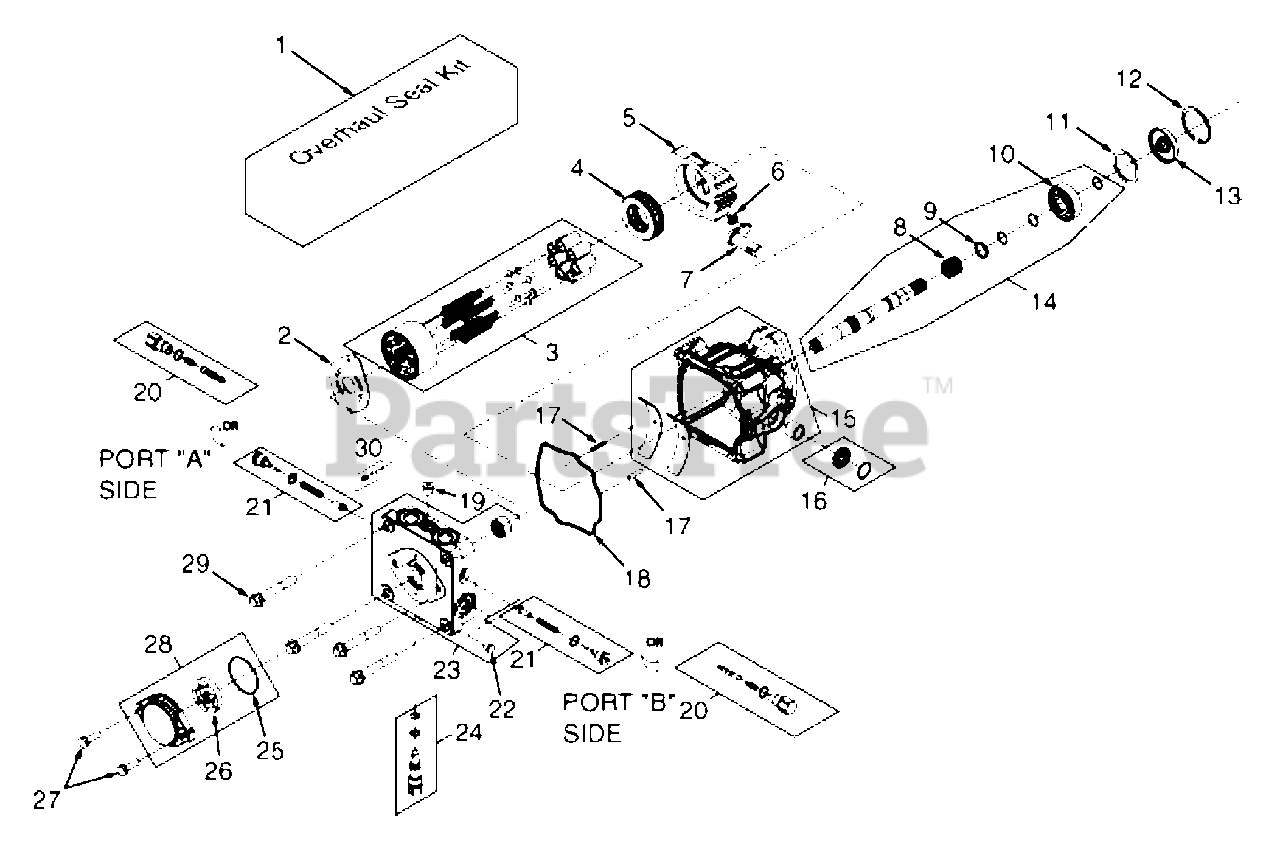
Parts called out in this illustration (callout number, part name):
1	Overhaul Seal Kit
2	Valve Plate
3	Cylinder Block Kit - 16cc
4	Thrust Ball Bearing Assembly
5	Variable Swashplate
6	Slot Guide
7	Trunnion Arm
8	Block Spring
9	Block Thrust Washer
10	Shaft Ball Bearing
12	Retaining Ring
14	Kit, Pump Shaft
15	Housing Kit
16	Trunnion Seal Kit
18	O-Ring
19	Straight Thread Plug
20	Shock Valve Kit (.031 Orifice)
21	Shock Valve Kit (.024 Orifice)
22	Straight Thread Plug
23	End Cap Kit
24	Bypass Valve Kit
26	Gerotor Assembly (.19 cu.in./rev.)
27	Socket Head Cap Screw (M8 x 1.25-25mm)
28	Charge Pump Kit (.19 STD. Splined)
29	Hex Screw, Flanged Head (M10 x 1.50-65mm)
30	Charge Relief Kit
